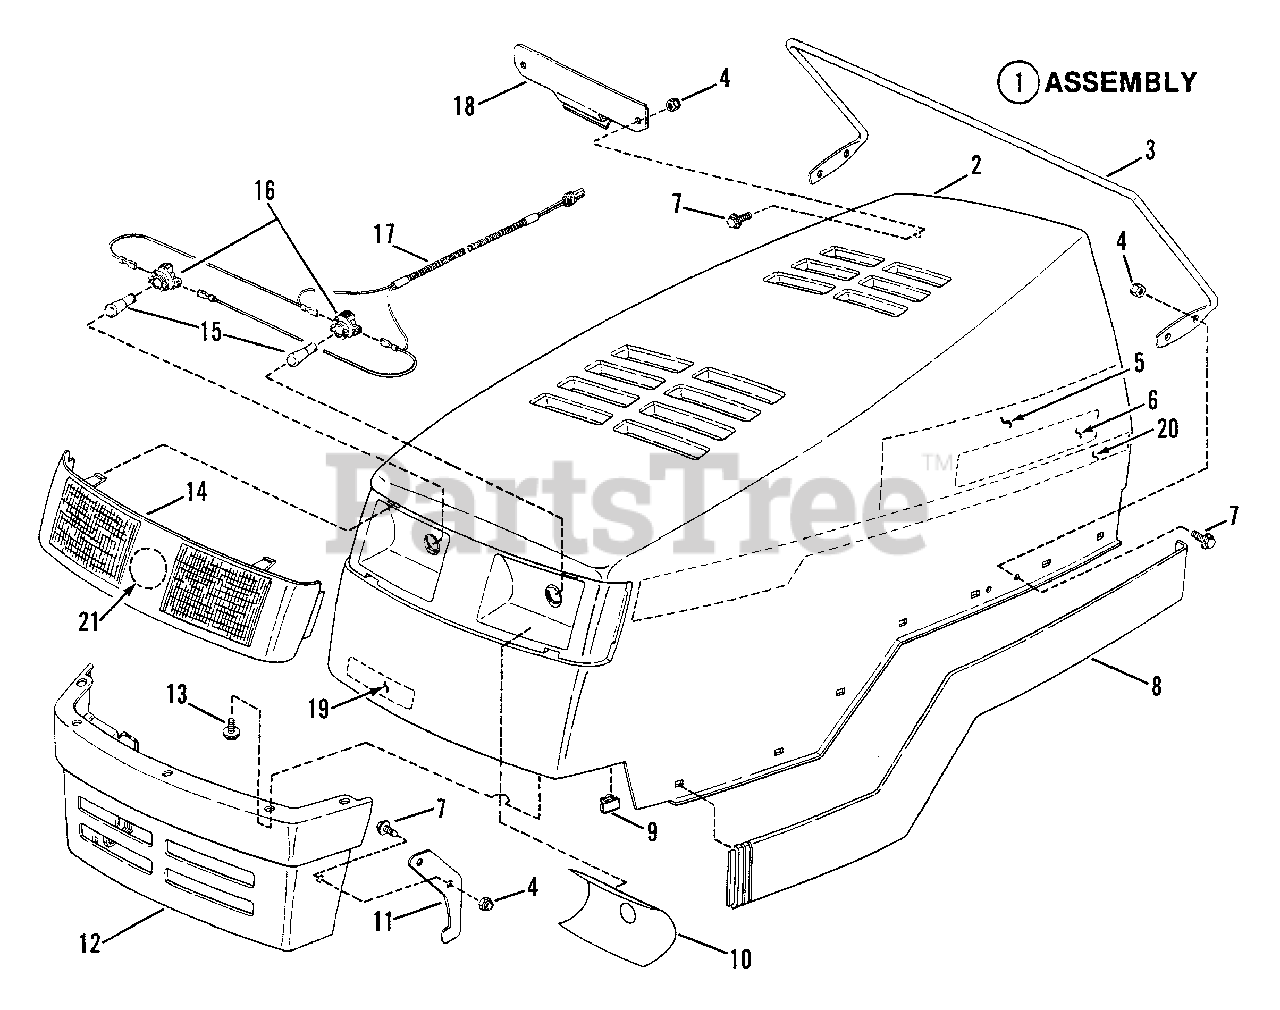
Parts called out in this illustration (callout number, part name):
1	KIT, Hood Assembly
2	HOOD (NLA)
3	ROD, Hood Latch
4	NUT, 1/4-20 Hex Lock
5	HEAT SHIELD, Hood
6	DECAL-SNAPPER, Molded Logo
7	SCREW, 1/4-20 x 5/8" Torx, Truss Head
8	BUMPER (R.H.) (NLA)
8	BUMPER (L.H. Shown) (NLA)
9	CLIP, Wiring Harness
10	DECAL, Reflect (R.H.)
10	DECAL, Reflect (L.H. Shown)
11	BRACKET, Latch Hook
12	BUMPER, Front
13	SCREW, #12 x 1/2"
14	LENS
15	BULB, Headlights
16	SOCKET, Headlight Bulb
17	HARNESS, Headlight Wiring
18	CLIP, Hood Latch
19	DECAL - SNAPPER, Molded Logo (LT125G33 & LT125G41)
19	DECAL - SNAPPER, Molded Logo (LT125G33)
20	DECAL, 1350LX (R.H.) (LT125G33 & LT125G41)
20	DECAL, 1350LX (L.H. Shown) (LT125G33 & LT125G41)
20	DECAL, 1350RX (R.H.) (RLT125G33)
20	DECAL, 1350RX (L.H. Shown) (RLT125633)
21	DECAL, Convertible (LT125G33)
21	DECAL, Twin-Turbo (LT125G41)
21	DECAL, Recycling (RLT125G33)
